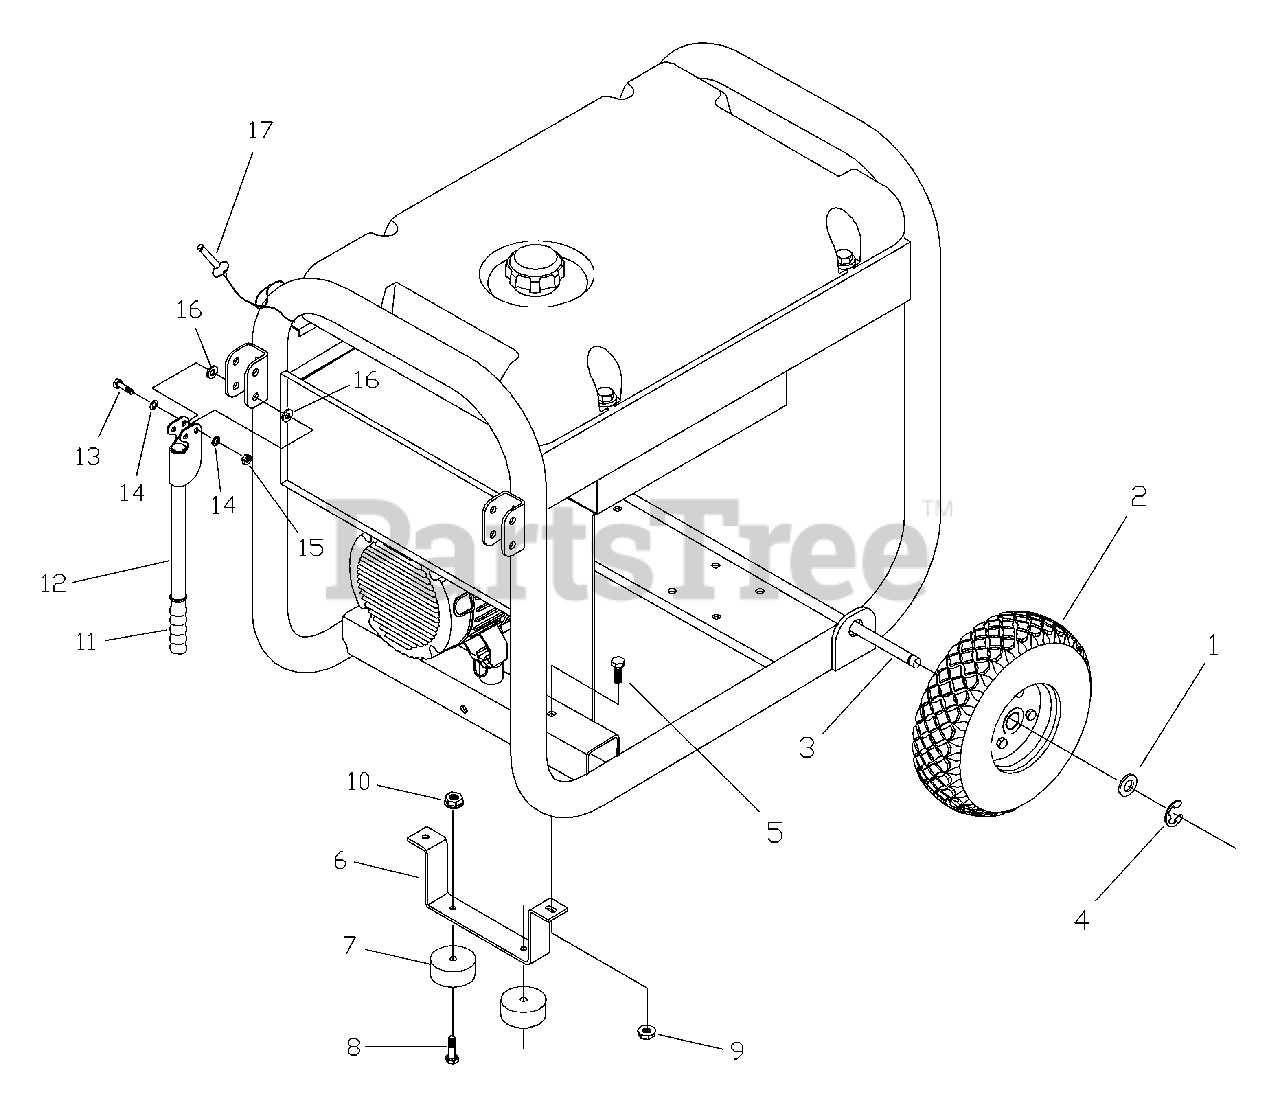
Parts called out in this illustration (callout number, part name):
3	AXLE, 5/8" x 24.80"
5	HHCS, M8 - 1.25 x 20 Lg.
6	ASSY, Bracket, Support w/ Vibe Mounts
7	MOUNT,Vibe
8	HHCS, 1/4 - 20 x 3/4 Lg.
9	NUT, M8 Flange Serrated
10	NUT, 1/4 - 20 Flange Nylok
11	GRIP, Handle
12	ASSY, Handle
15	NUT, M8 Nylok
16	WASHER, 1.2 x 0.346 x 0.03, Nylon
17	PIN, with Lanyard
